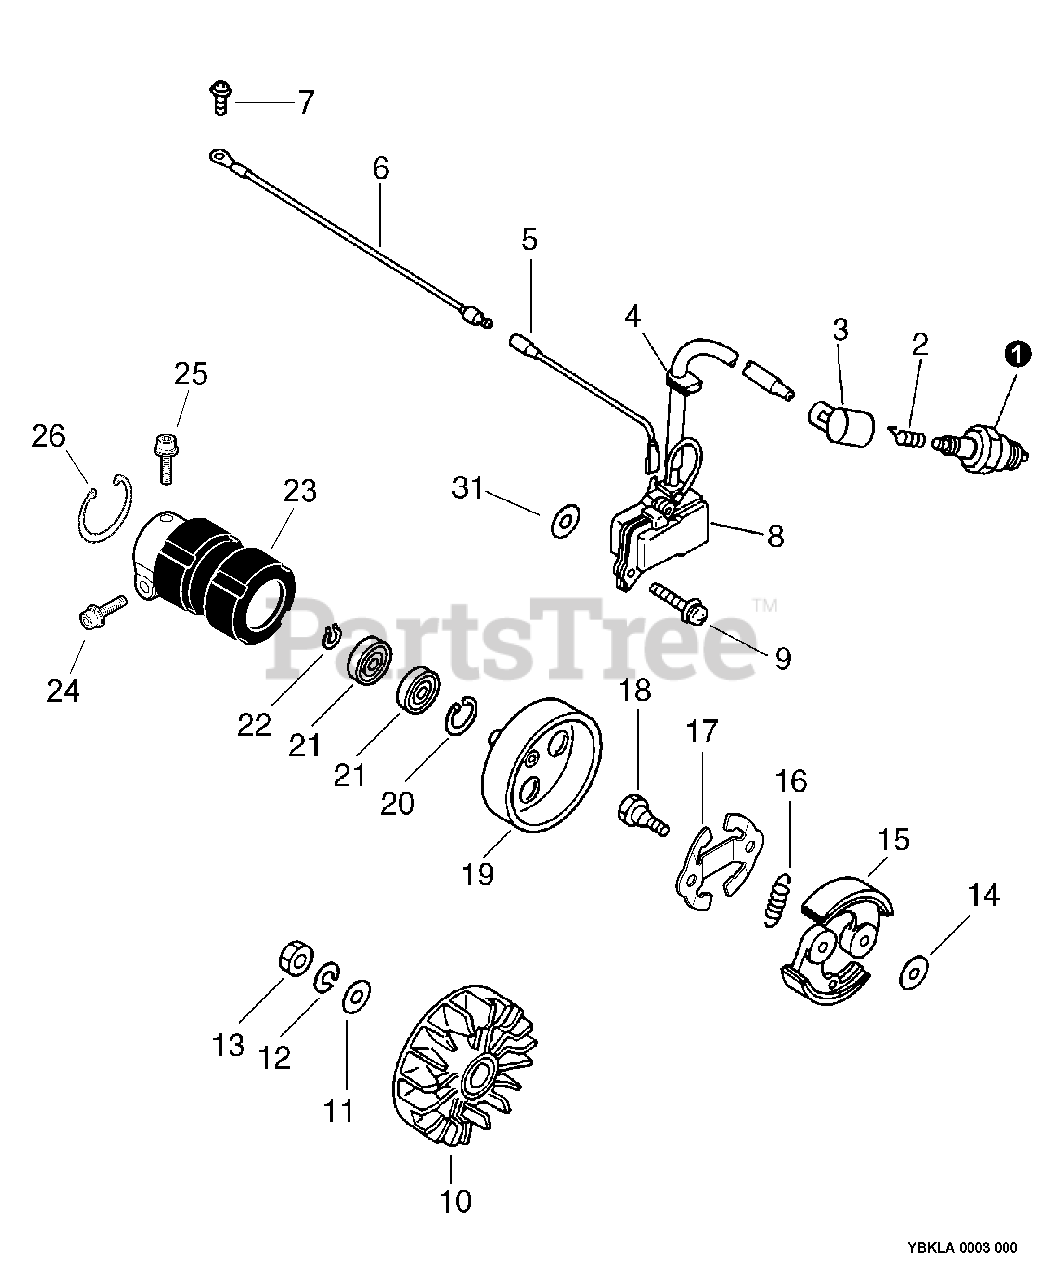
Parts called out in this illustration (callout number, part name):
1	SPARK PLUG -- BPM-7A
2	TERMINAL, SPARK PLUG CAP
3	CAP, SPARK PLUG
5	LEAD - IGNITION
6	LEAD - GROUND
7	SCREW - 5X10
8	COIL, IGNITION
9	SCREW - 5X20
10	FLYWHEEL
11	WASHER - 10
12	LOCKWASHER - 10
13	NUT - 10
15	SHOE, CLUTCH
16	SPRING, CLUTCH
17	PLATE, SPRING
18	BOLT, CLUTCH
19	DRUM, CLUTCH
20	RING, RETAINING - 28
21	BEARING, BALL - 6001
22	RING, RETAINING - 12
23	CUSHION
24	SCREW - 5X28
25	SCREW - 5X12
26	RING, RETAINING - 45
